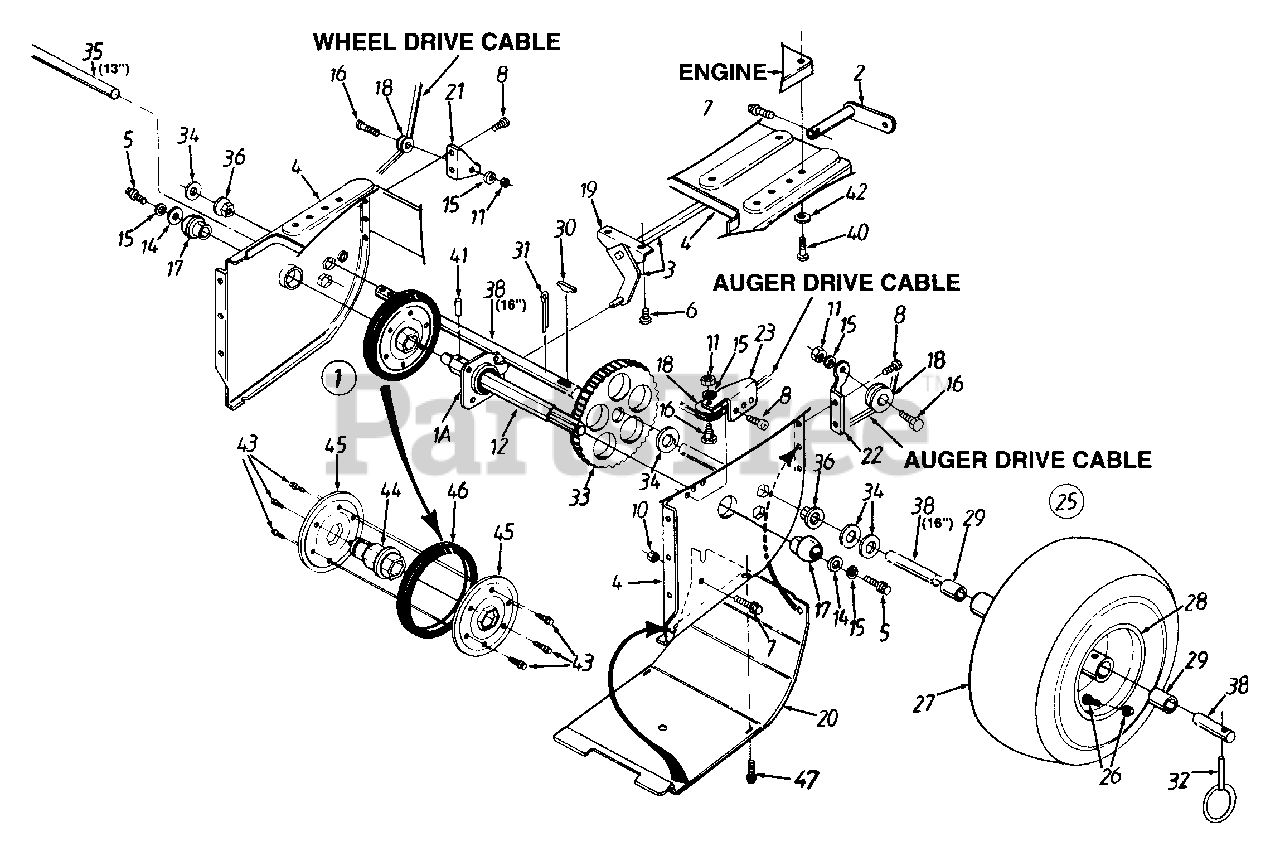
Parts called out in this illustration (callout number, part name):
1	Friction Wheel Ass'y. Comp.
1A	Friction Wheel Brg. Ass'y.
2	Shift Arm Ass'y.
3	Shift Rod Ass'y.
6	Hex Tap Scr. 1/4-20 x .38" Lg.
7	Hex Wash. Hd. TT-Tap Scr. 1/4-20 x 1" Lg.
8	Torx Mach. AB-Tap Scr. 1/4 x .62" Lg.
10	Hex Nut 1/4-20 Thd.
11	Hex Jam Nut 1/4-20 Thd.
12	Gear Shaft
14	Fl-Wash. .265" I.D. x .938" O.D.
15	L-Wash. 1/4" I.D.
16	Shld. Bolt 5/16 Dia. x .35" Lg.
17	Ball Brg. w/Snap Ring
18	Cable Roller Guide
27	Tire Only (666H)
30	#9 Hi-Pro Key 3/16" x 3/4" Dia.
31	Cotter Pin 5/32" x 1-1/4" Lg.
32	Klik Pin
33	79 Tooth Gear
34	Fl-Wash. .76" I.D. x 1.49" O.D.
35	Wheel Axle (616E)
36	Hex Flange Brg. .752" I.D.
38	Wheel Axle (646F & 666H)
40	Hex Bolt 3/8-16 x 1.25"
41	Spr. Roll Pin 1.12" Lg.
42	Fl-Wash. .406" I.D. x 1" O.D.
43	Hex Wash. Hd. TT-Tap Scr. 1/4-20 x .5" Lg.
44	Friction Wheel Hub
45	Friction Plate
46	Friction Wheel Rubber
47	Hex Wash. Tap Scr. 3/8" Lg.
